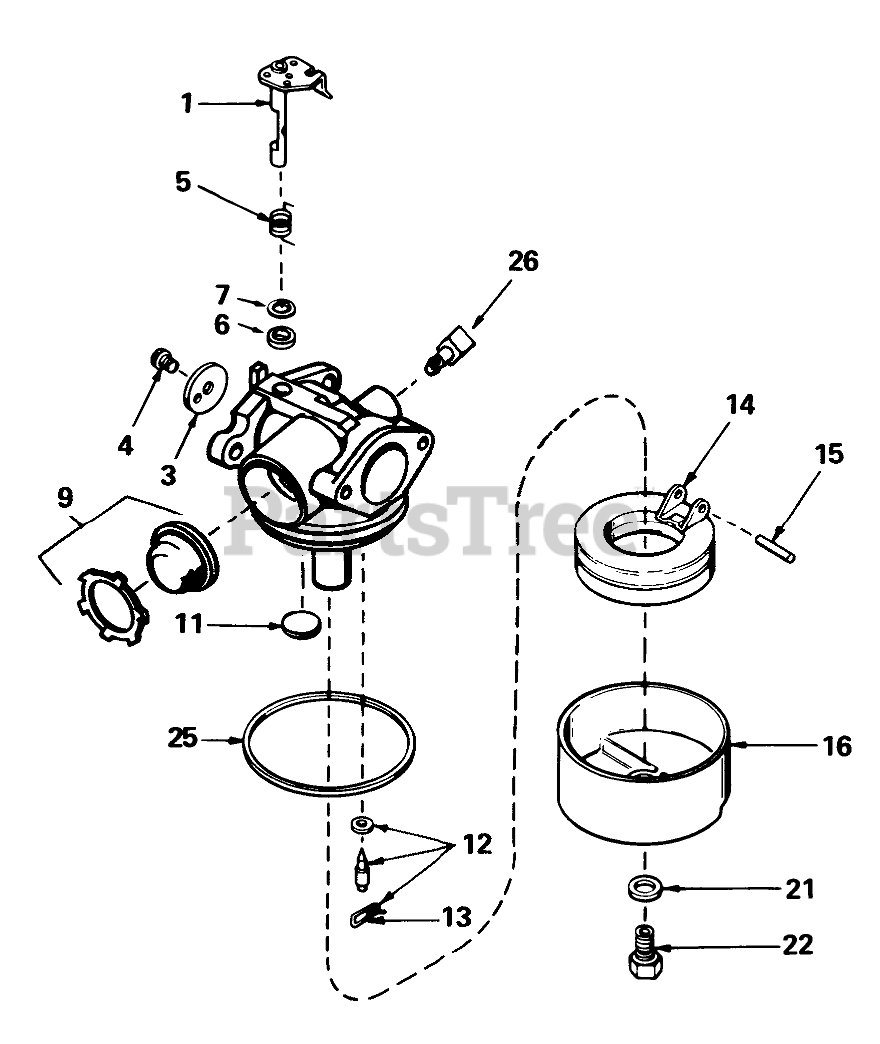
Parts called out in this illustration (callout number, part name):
1	Throttle Shaft and Lever ASM
3	Throttle-Shutter
4	Screw-Shutter
5	Spring-Return, Throttle
6	Seal-Dust
7	Washer-Seal, Dust
9	Primer Assy.
11	Plug-Welch, Atmospheric Vent
12	Inlet Needle-Seat & Clip Assembly (Incl. Ref. #13)
13	Clip-Spring
14	Float
15	Shaft-Float
16	Bowl Float
21	Gasket-Bowl
22	Nut-Float Bowl
25	O Ring-Bowl, Float
26	Fitting-Fuel
